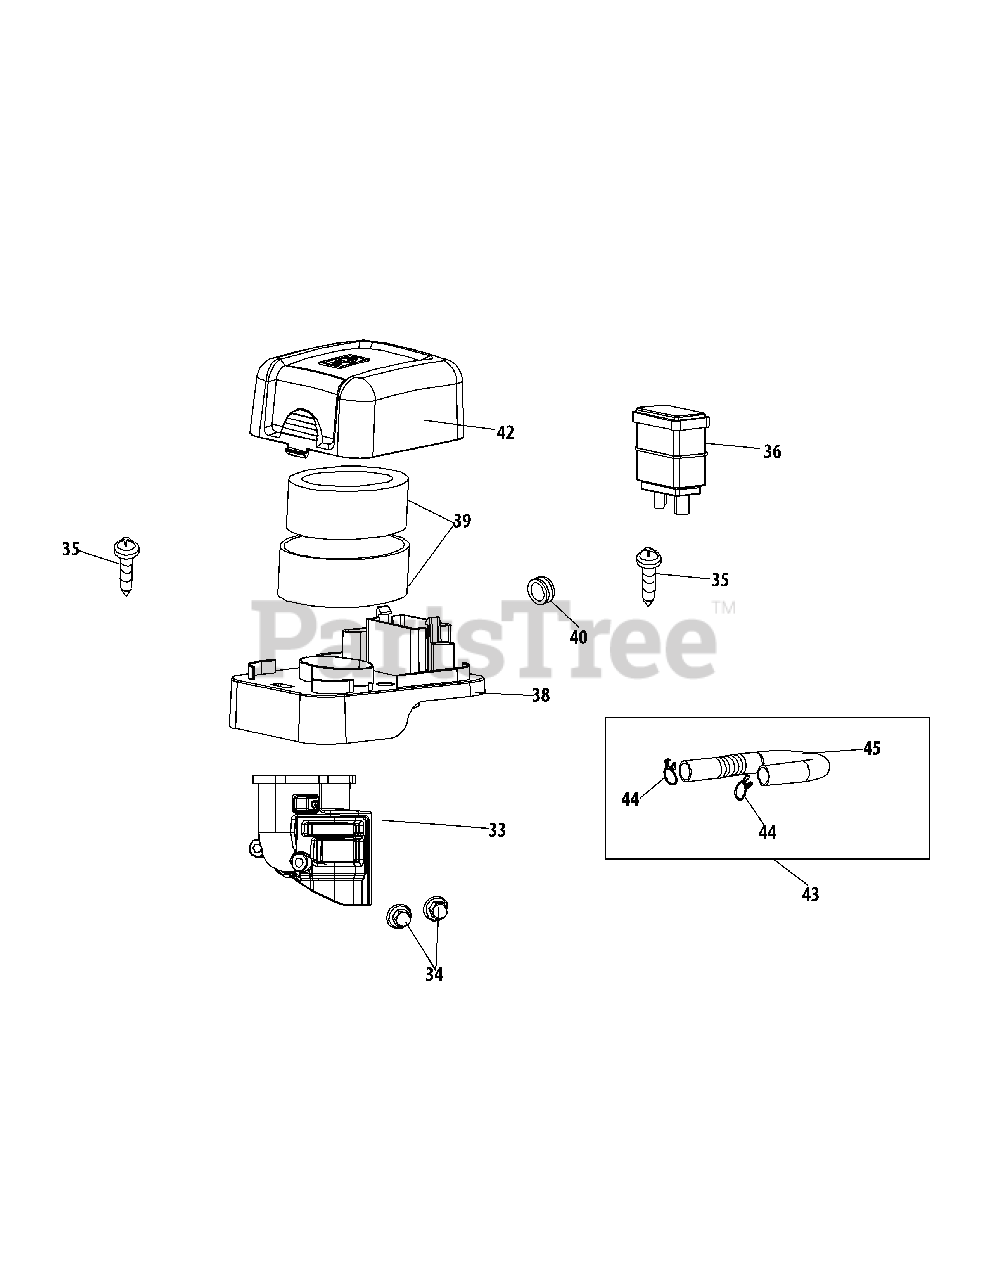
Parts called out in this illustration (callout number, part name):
33	Air Cleaner Housing
35	Self-Tapping Bolt4.2×16
36	Carbon Canister
38	Silencer Plate
39	Air Filter Assembly
40	Damper Gasket
42	Air Cleaner Cover
43	Primer Hose
45	Exhaust Piping
